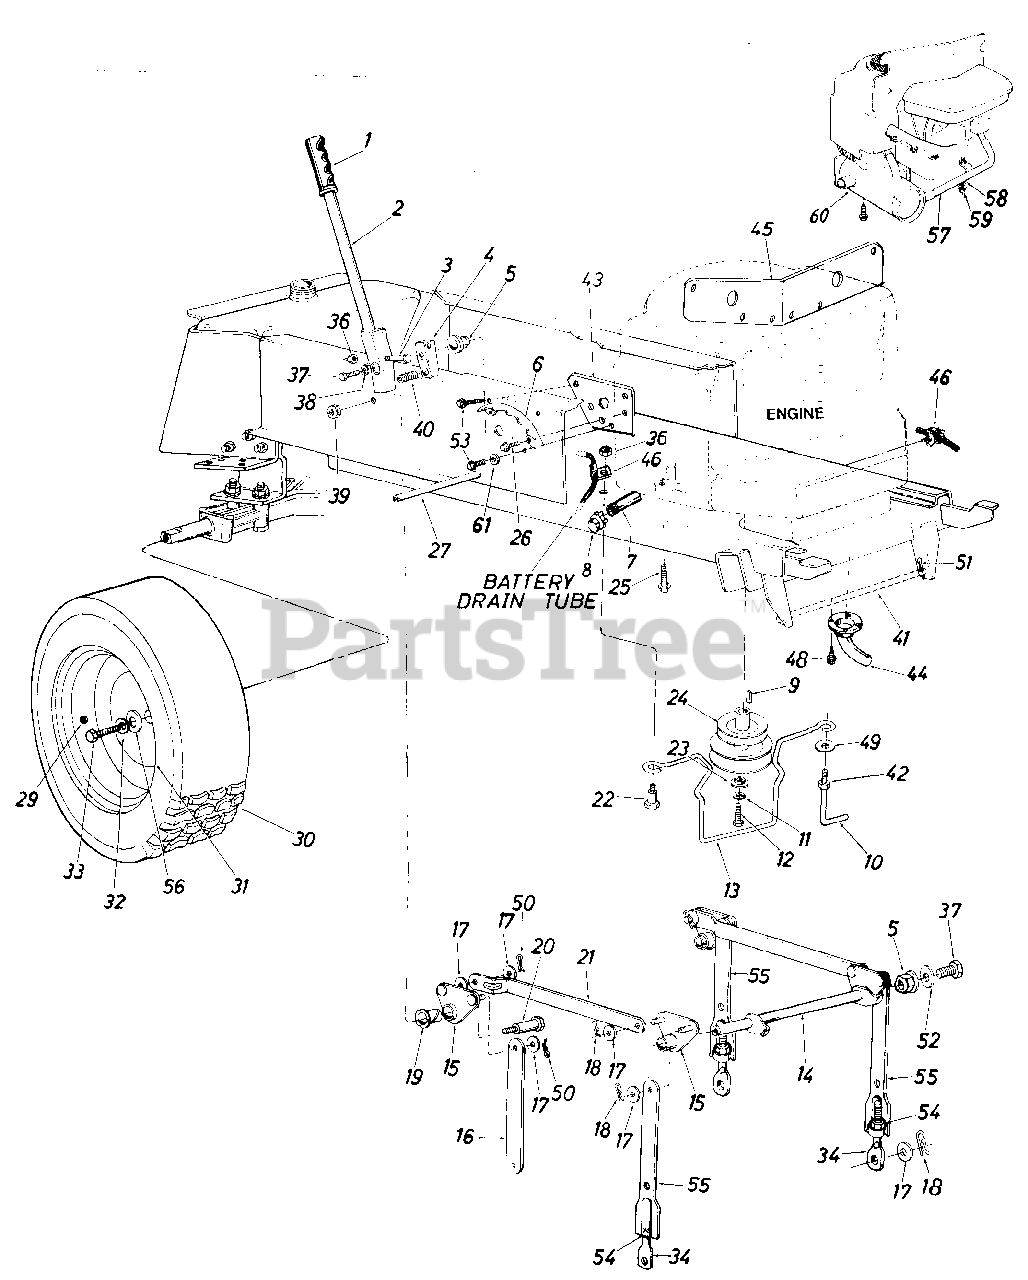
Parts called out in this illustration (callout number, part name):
1	Grip
2	Lift Handle Ass'y.
3	Hex Scr. 5/16-18 x 1.50" Lg.
4	Lift Shaft Drive
5	Plastic Hex Brg. 5/8" I.D.
8	Pipe Cap 3/8-18 Npt.
9	Sq. Key 1/4" x 1.50"
10	Belt Guard Lock Pin
11	L-Wash. 7/16" Scr.
12	Hex Scr 7/16-20 x 1.50" Lg.
13	Belt Guard
14	Lift Shaft Ass'y.
15	Lift Pivot Brkt. Ass'y.
17	Fl-Wash. 1/2" I.D. x 1.00" O.D. x .090
18	Hairpin Cotter
19	Nyliner 5/8" I.D. x .88" Lg.
20	Shld. Scr. 5/8" Dia. x .9..6" Lg. 3/8-16
23	Flat Wash. .44" I.D. x 1.25" O.D. x .17
24	Two-Step Engine Pulley
25	Hex Wash. Hd. Scr. 3/8-16 x 1.25" Lg.
26	Hex Thd. Rolling Scr. 5/16-18 x .75" Lg.
27	Running Board Rod
29	Air Valve
30	Rear Wheel Ass'y. Comp.
31	Rear Wheel Rim Only
32	Bell-Wash. .345" I.D. x .88"
33	Hex Bolt 5/16-24 x .75" Lg.
34	Eye Bolt Adj. Link 1/2-13 Thd.
36	Hex Cent. L-Nut 5/16-18 Thd.
37	Hex Scr. 5/16-24 x .62" Lg.*
38	L-Wash. 5/16" I.D.
39	Hex Center L-Jam Nut 3/8-16 Thd.
40	Compression Spring
41	Deck Connecting Rod
42	Hex Nut 5/16-24 Thd.
45	Heat Shield
46	Mounting Clamp
48	Hex Wash. Hd. AB-Tap Scr. #10 x .50" Lg.
49	Bell-Wash. .39" I.D.
50	Cotter Pin .09 Dia. x 1.0" Lg.
51	Int. Cotter Pin
52	Flat Wash. .34" I.D. x 1.12" O.D. x .125
53	Hex Wash. Hd. AB-Tap Scr. 5/16 x .62" Lg.
54	Hex Nut 1/2-13 Thd.
56	Fl-Wash. .34" I.D. x 2.0" O.D.
57	Inlet Tube
58	Spec. L-Wash. 5/16" I D
59	Hex Nut 5/16-18 Thd
60	Muffler
61	Flat Wash. .344" I.D.
